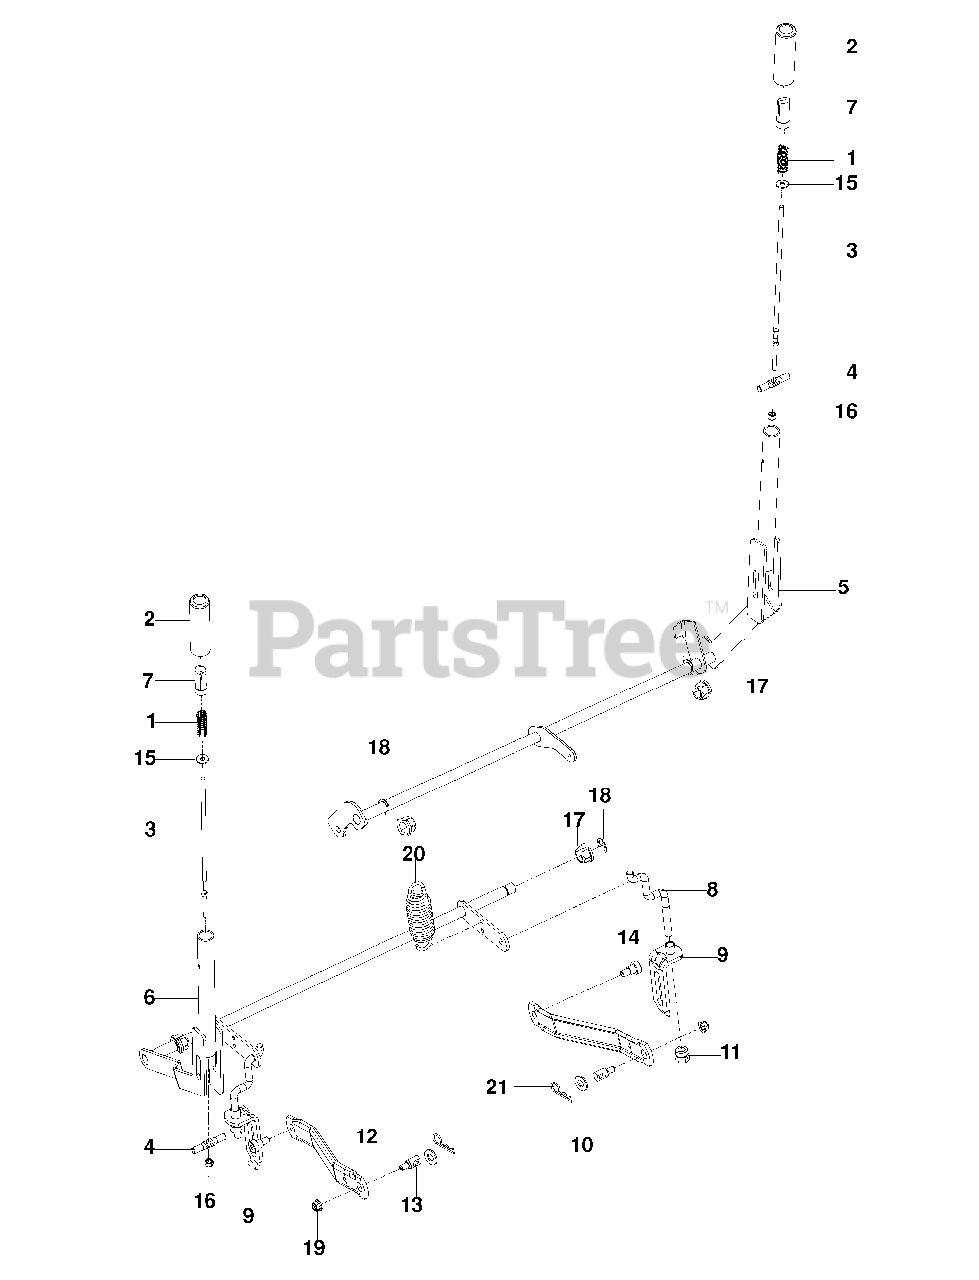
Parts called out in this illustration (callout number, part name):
1	SPRING, COMPRESSION
2	GRIP, HANDLE BLK
3	ROD, HANDLE RELEASE
4	ROD, LATCH RELEASE
5	SHAFT, BRAKE BLK
6	ARM, LIFTING
7	BUTTON, PUSH BLK
8	LINK, REAR SUSPENSION
9	BRACKET, LIFT
10	WASHER 5/8 SAE FLT
11	NUT, LIFT LINK
12	ARM, SUSPENSION RR
13	STUD w/ANTI- ROTATE
14	BOLT 3/8-16 x 3/8 SKT HD
15	WASHER 1/4 FLT
16	NUT 1/4-20 HEX NYLOC
19	NUT 5/16-18 FLANGE NYLOC
